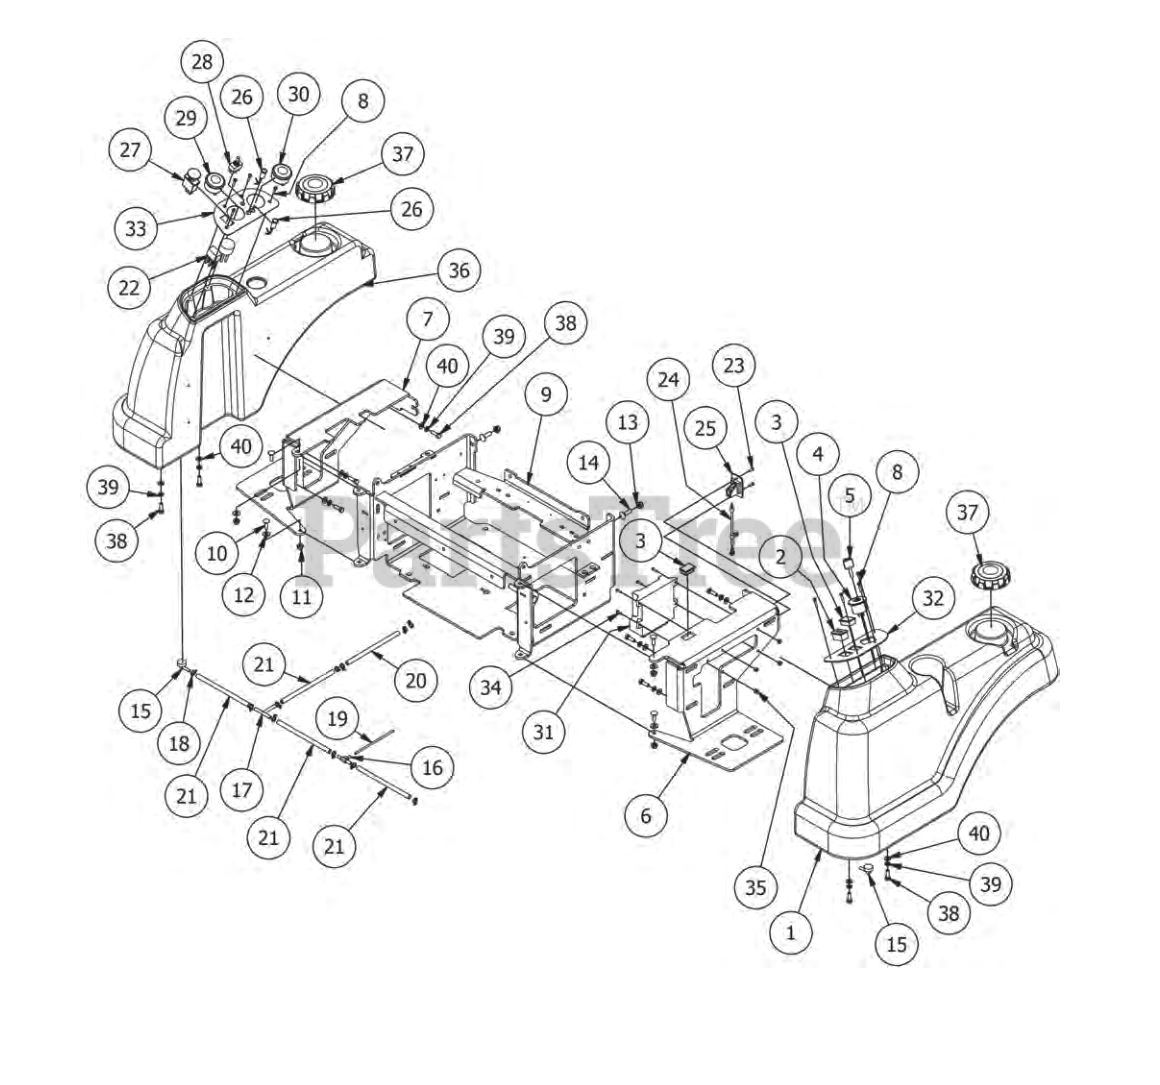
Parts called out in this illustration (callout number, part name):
1	Left Fuel Tank with Fender
2	Tachometer
3	Light Plug
4	Ignition Switch
5	Ignition Key
6	Tank Supports-Left
7	Tank Support-Right
8	10-32 x 1 Button Head Bolt
9	Diesel Seat Frame
10	5/16" x 1" Carriage Bolt
11	5/16" Flange Nut
12	.360 ID Plastic Washer
13	3/8" Nylock Flange Nut
14	3/8" x 1 1/4" Carriage Bolt
15	Fuel Tank Hose Nipple w/ Filter
16	Brass fuel line T
17	fuel line T
18	1/4 fuel clamp
19	3/16 Fuel Line
20	5/16" fuel line hose
21	1/4" fuel line hose
22	Wiring Harness
23	3/16 Rivet
24	2015 Seat Latch Cable
25	2015 Seat Latch Toggle
27	PTO Engager
28	Deck Lift Joystick
29	2" Water Temperature Gauge
30	2" Oil Pressure Gauge
31	ECM for 1100cc Diesel
32	Control Panel (Left)
33	1100cc Diesel Control Panel
34	10-24 X 5/8 BS C/S 18-8 SS
35	10-24 Nylon Insert Locknut
36	Right Fuel Tank with Fender
37	Diesel Fuel Cap-3.5 inch Neck
38	5/16" x 1" Bolt
39	5/16" Lock Washer
40	5/16" Flat Washer
